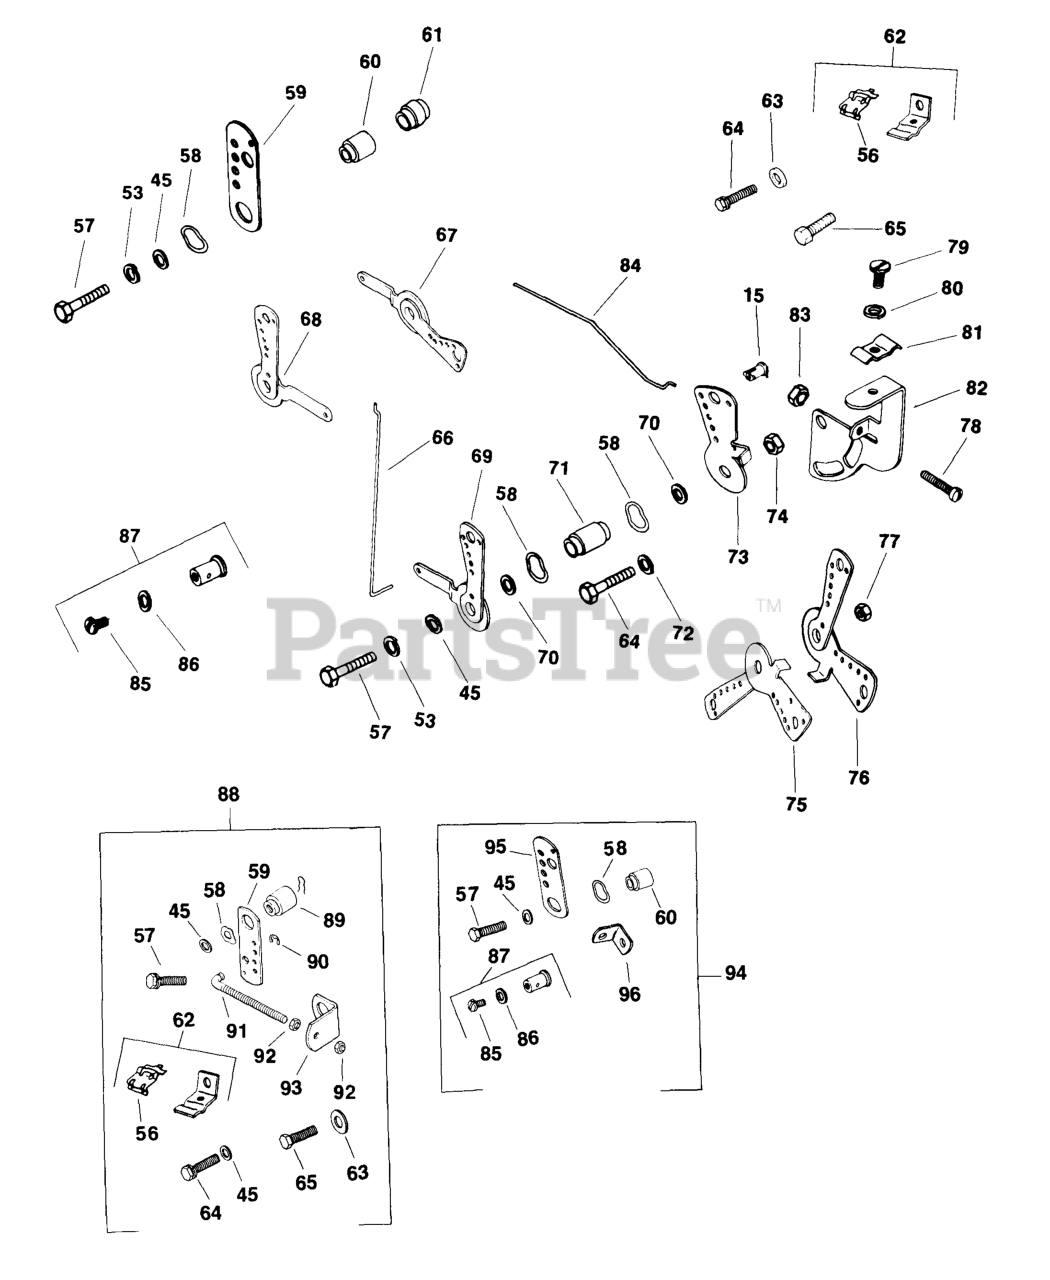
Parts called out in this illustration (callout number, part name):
15	BUSHING-DISCONTINUED
45	WASHER, FLAT 1/4" (O.D. 1/2")
53	WASHER, SPRING LOCK 1/4"
57	SCREW, CAP HD 1/4-20x1-1/2" - DISCONTINUED
58	WASHER, SPRING 11/32"
59	BRACKET-DISCONTINUED
61	SPACER USE 25 112 10-S
70	WASHER - DISCONTINUED
71	SPACER
72	WASHER, FLAT 1/4"
73	LEVER - DISCONTINUED
74	NUT, JAM 1/4-20 GRADE 2 USE 25 100 19-S
78	SCREW, SPECIAL
79	SCREW, WSH HD TAP #10-24X3/4" USE 25 086 97-S
81	CLAMP, DUAL CONDUIT
83	NUT, MACH SCREW #8-32 GRD 2 USE 25 100 16-S
85	SCREW - USE 41 086 20
86	WASHER, FLAT 1/4"
87	KIT, CLAMP
